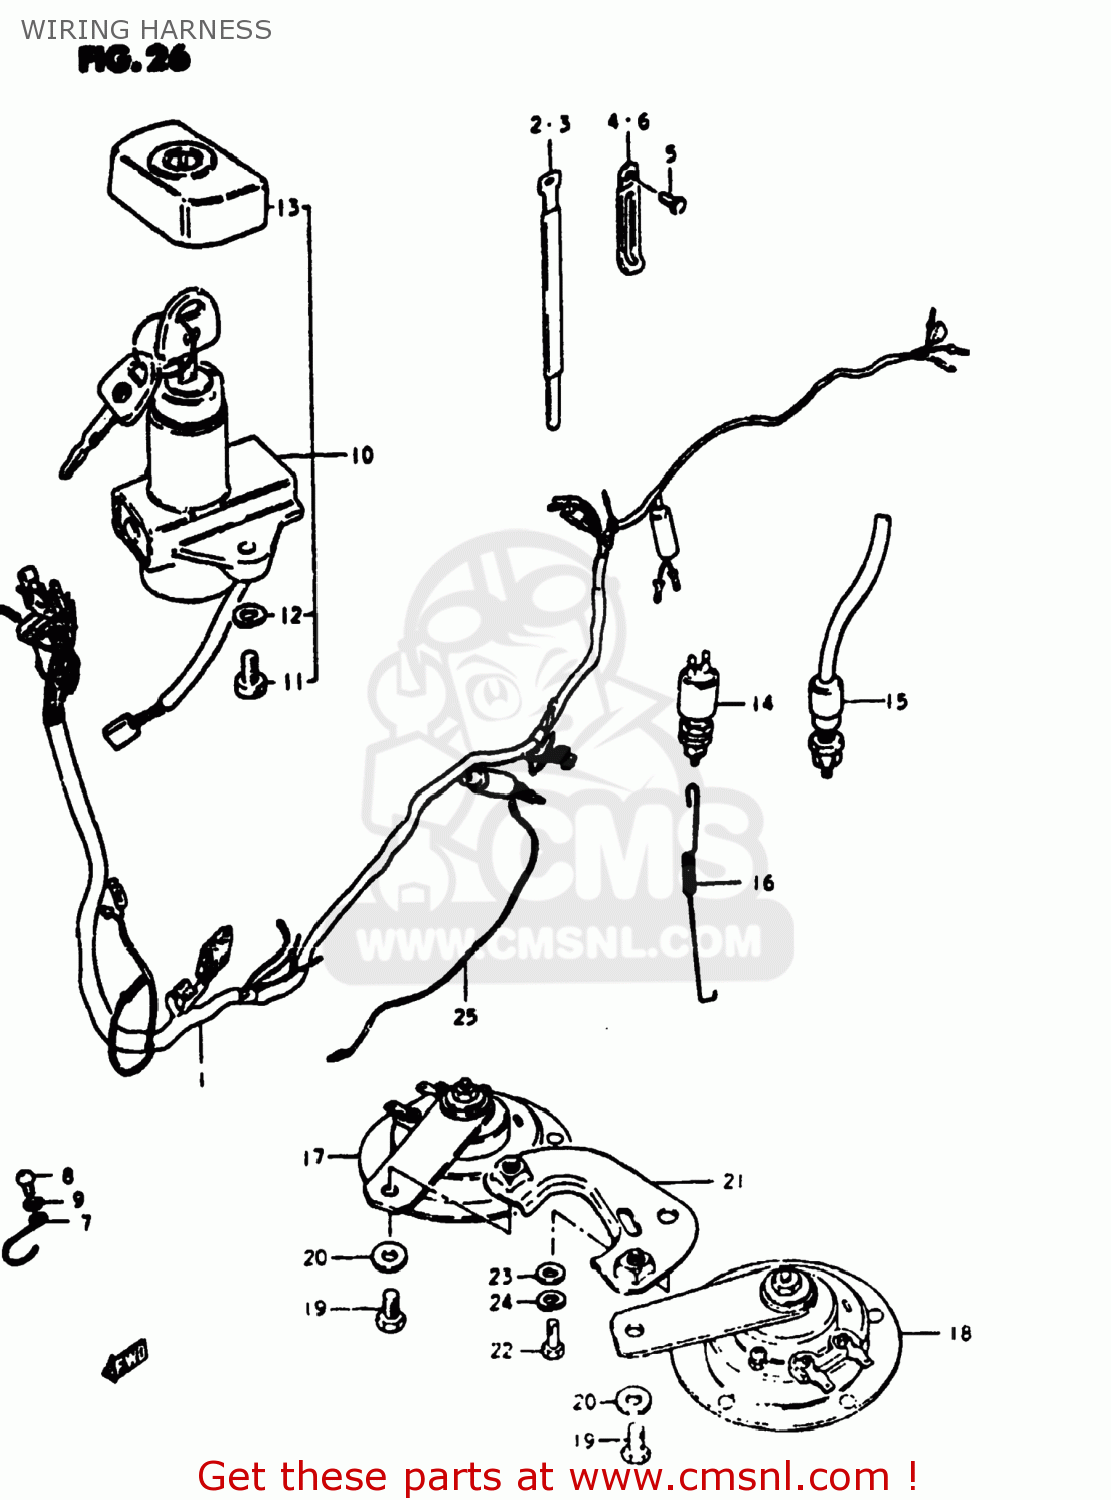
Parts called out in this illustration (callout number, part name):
1	HARNESS,WIRING
2	CLAMP(L:120)
3	CLAMP
4	CLAMP
5	BOLT
6	CLAMP
7	GUIDE,WIRING HARNESS
8	SCREW 6X12
9	WASHER 6MM
10	LOCK ASSEMBLY,STEERING
11	BOLT
12	LOCK WASHER
13	CAP,IGNITION SWITCH
14	SWITCH ASSEMBLY,STOP LAMP
15	SWITCH ASSY,BRAKE LAMP
16	SPRING
17	HORN ASSEMBLY,LOW PITCH
18	HORN ASSEMBLY,HIGH PITCH
19	BOLT 8X12
20	WASHER
21	BRACKET,HORN
22	BOLT
23	WASHER
24	LOCK WASHER
25	WIRE
